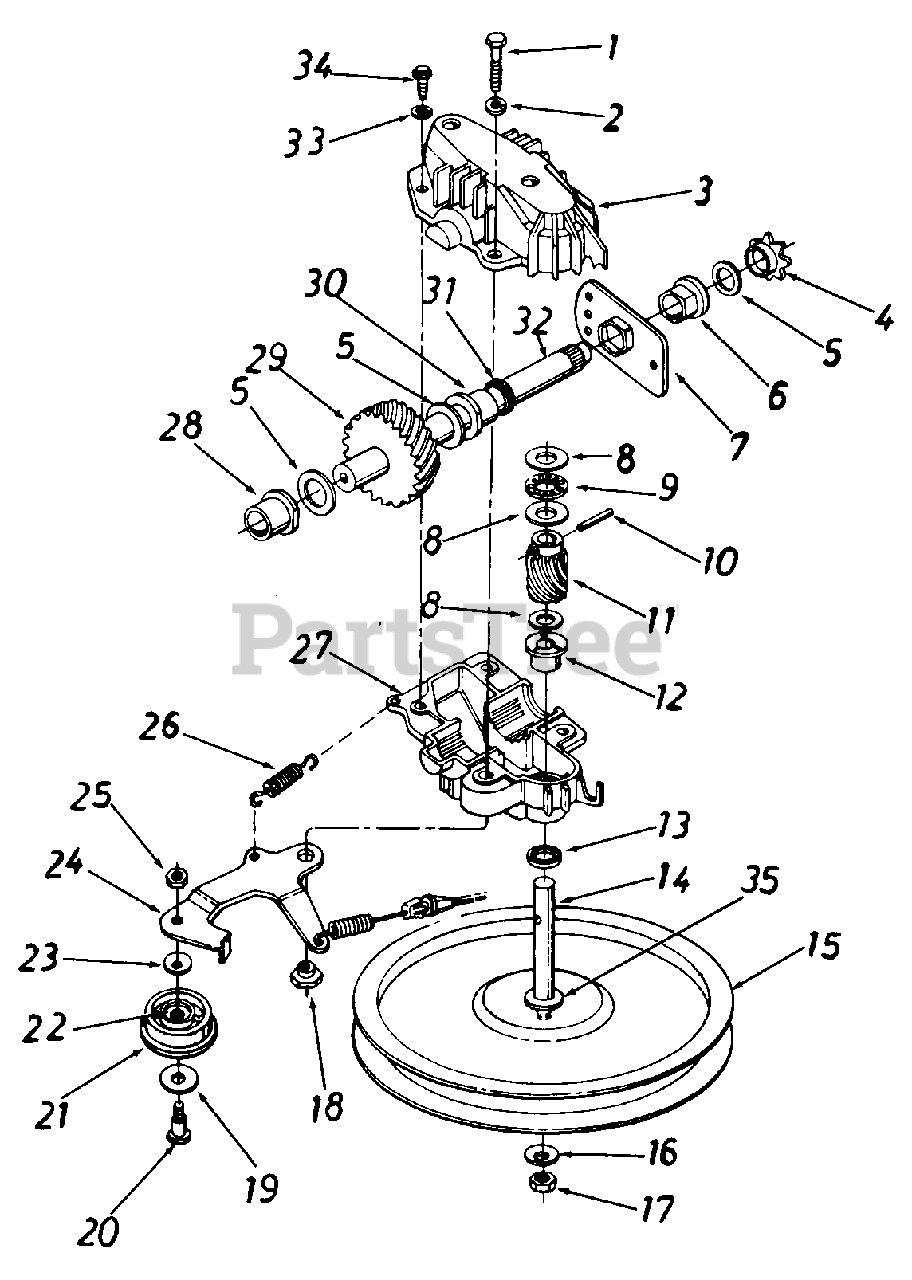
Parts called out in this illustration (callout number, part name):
1	Hex Bolt 1/4-20 X 1.25" Lg.
2	L-Wash. 1/4" I.D.
3	Upper Transmission Hsg. Half
4	#48 Sprocket 7 Tooth x 1/2 Pitch
5	Fl-Wash. 5/8" I.D. x .030
6	Hex Flange Brg. .631" I.D.
7	Hex Bearing Cup
8	Thrust Wash. .382" I.D. x .70" 0.D.
9	Thrust Bearing .375" I.D. x .812" O.D.
10	Spring Pin Spir. 1/8" X .62" Heavy
11	11 Tooth Helical Gear
12	Flange Bearing
13	Oil Seal
14	Pulley-Transmission Shaft .375 O.D.
15	Fl-Pulley 5.06" O.D.
16	Bell-Wash. .265" I.D. x .75" O.D.
17	Hex Lock Nut 1/4-28 Thd.
18	Shld. Spacer .375" Dia. x . 170
19	Fl-Wash. .390" I.D. x 1.0" O.D.
20	Shld. Bolt .375" Dia. x .40"
21	Fl-Idler Plastic 1.50" Dia. x .48
22	Needle Brg. .375" x .31
23	Bell-Wash . .265" I.D. x .75" O.D.
24	Idler Brk't. Ass'y.
25	Hex Patch L-Nut 1/4-28 Thd.
26	Extension Spring 1.12" Lg.
27	Lower Transmission Hsg. Half
28	Flange Bearing .566 Dia.
29	33 Tooth Helical Gear
30	Flange Bearing .629 Dia.
31	Oil Seal .625 Dia.
32	Gear Sprocket Shaft
33	L-Wash. #10
34	Hex B-Tap Scr. #10 x .62"
35	Hex Washer .26" x .88" x .04
